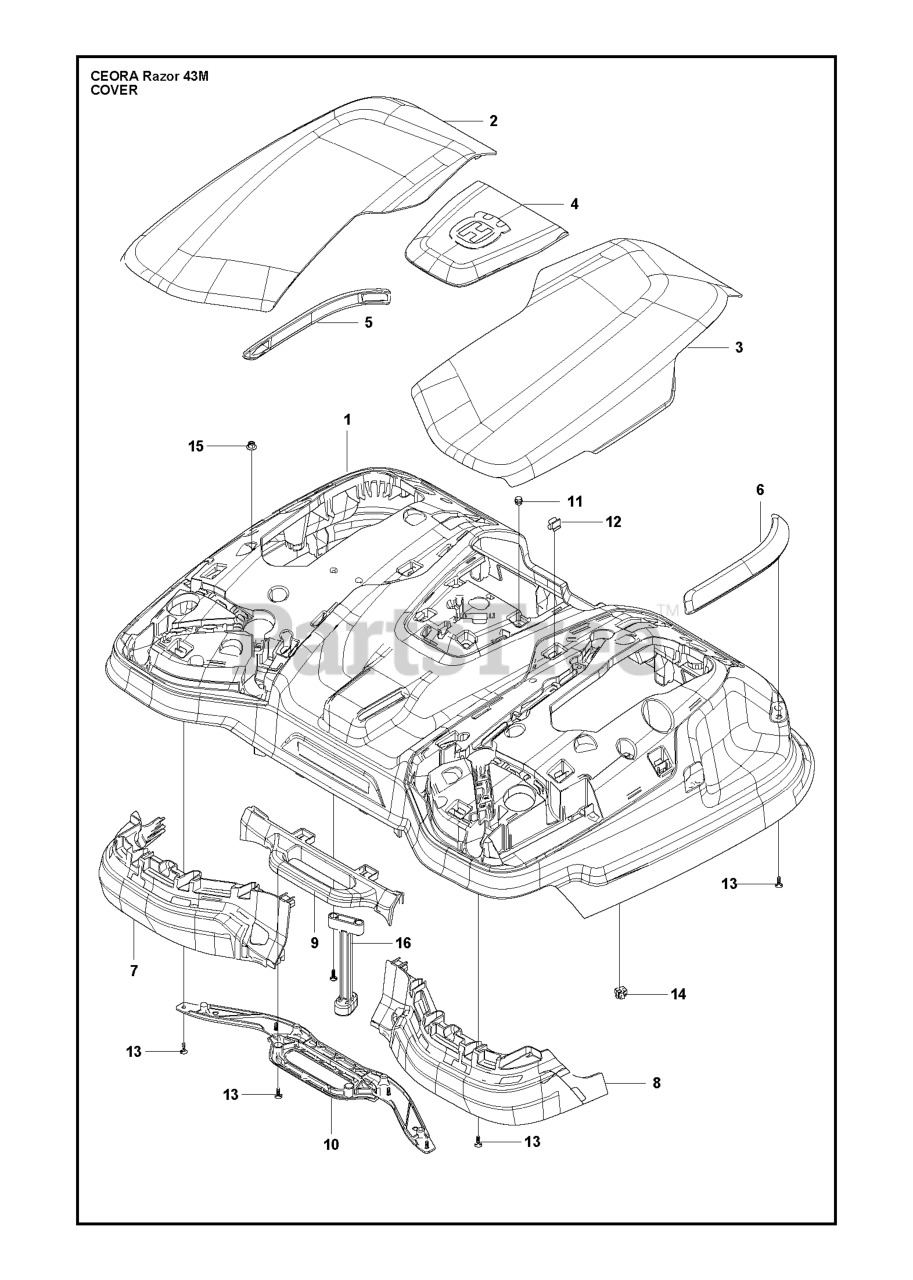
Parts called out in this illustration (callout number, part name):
1	BODY CUTTING DECK
2	COVER
3	COVER
4	COVER ASSY LOGO PLATE
5	HANDLE
6	HANDLE
7	BUMPER
8	BUMPER
9	HANDLE
10	HANDLE
11	MAGNET
12	Clips
13	SCREW ITXPANT
14	INSERT SCREW BLOCK
15	NUT FLANGE
16	SUPPORT PROTECTION PLATE
